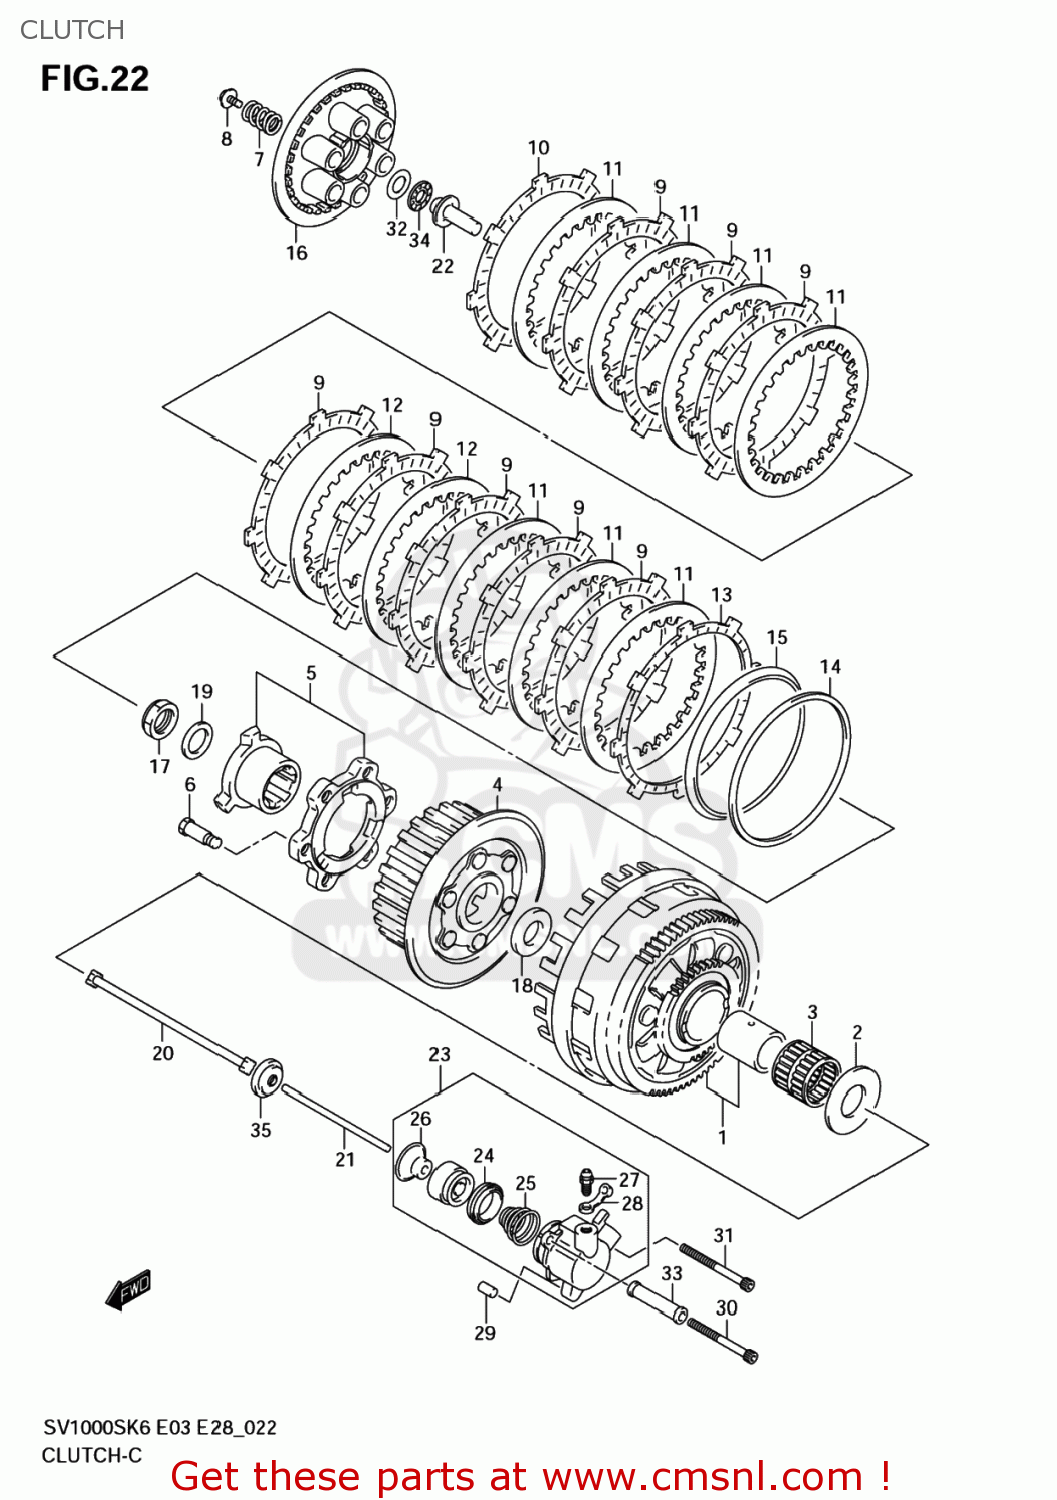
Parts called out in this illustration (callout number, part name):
1	GEAR ASSY,PRI DRIVEN
2	WASHER(25X52X2.5)
3	BEARING(35X40X39.8)
4	HUB,CLUTCH SLEEVE
5	CAM SET,CLUTCH
6	BOLT,CLUTCH SPRING SUPPORT
7	SPRING,CLUTCH
8	BOLT,CLUTCH SPRING
9	PLATE,CLUTCH DRIVE NO.1 (NAS)
10	PLATE,CLUTCH DRIVE NO.2 (NAS)
11	PLATE,CLUTCH DRIVEN NO.1(T:2.0 (NAS)
12	PLATE,CLUTCH DRIVEN NO.2(T:2.3 (NAS)
13	PLATE,CLUTCH DRIVE NO.3 (NAS)
14	SEAT,WAVE WASHER
15	WASHER,CLUTCH PLATE WAVE
16	DISC,CLUTCH PRESSURE
17	NUT
18	WASHER(25X50X5.8)
19	WASHER
20	ROD,CLUTCH
21	ROD,CLUTCH PUSH,L
22	PIECE,CLUTCH PUSH
23	CYLINDER,CLUTCH RELEASE
24	CUP
25	SPRING,CLUTCH CYLINDER
26	COVER,DUST
27	BLEEDER
28	CAP,BLEEDER
29	PIN
30	BOLT
31	BOLT
32	WASHER(15.5X28X1)
33	SPACER,CL RLSE CYL
34	BEARING(15X28X2)
35	SEAL,OIL(6X34X10.5)
